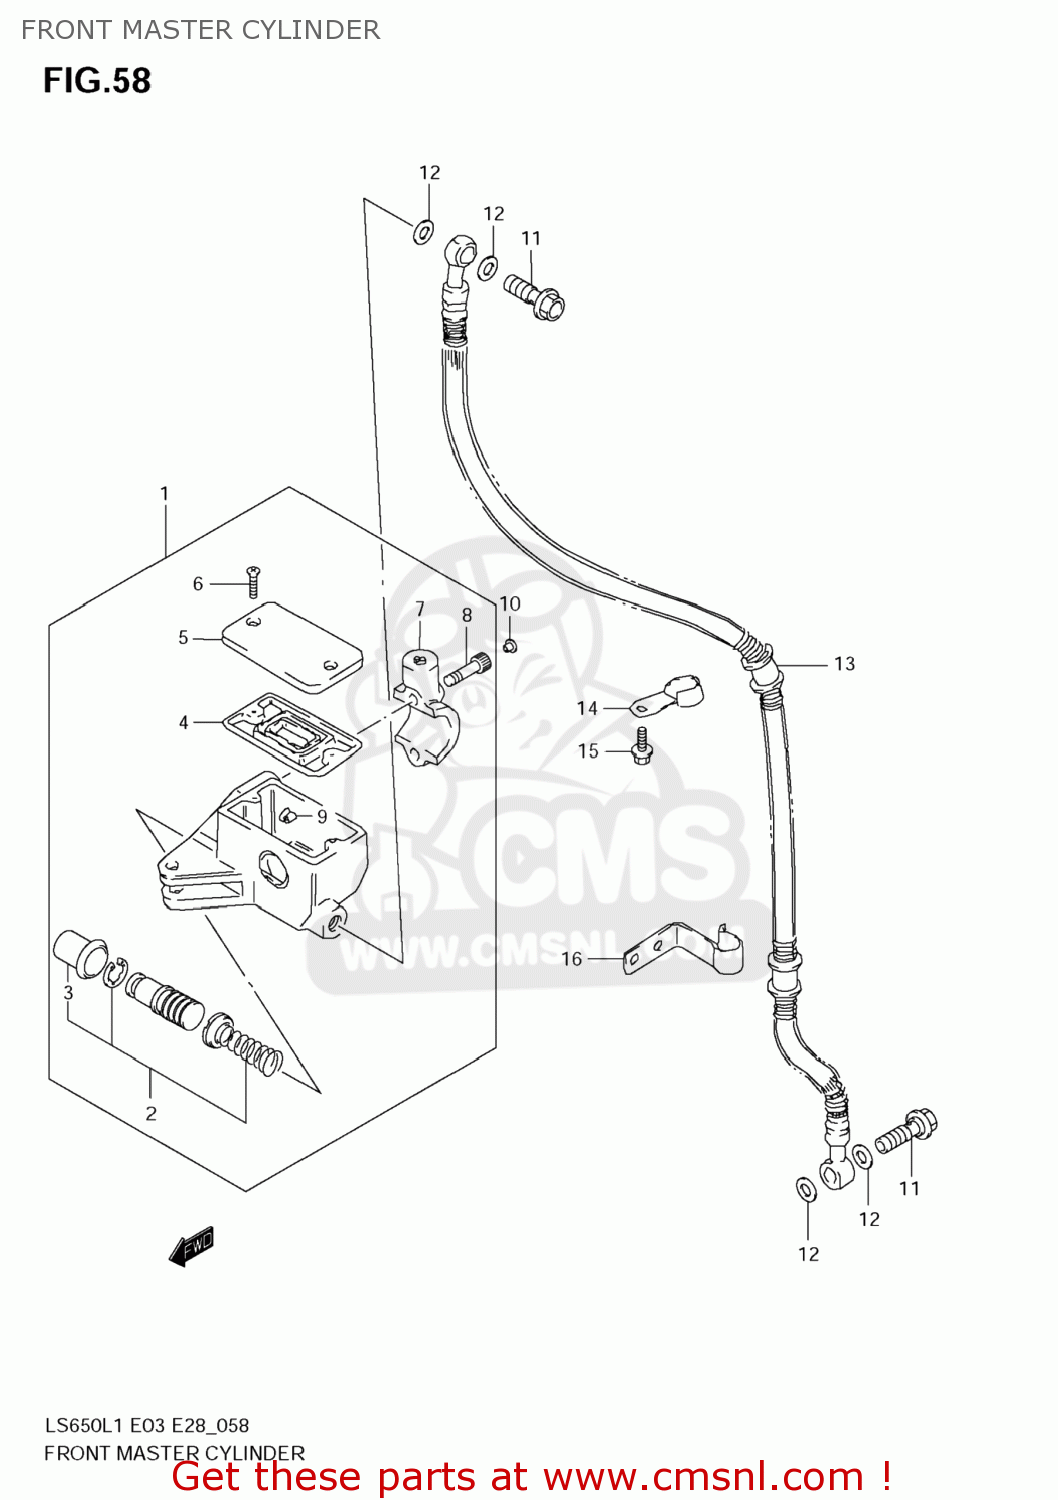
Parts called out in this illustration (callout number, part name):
1	CYLINDER ASSY,FR MASTER
2	PISTON/CUP SET
3	BOOT
4	5
5	CAP
6	SCREW
7	HOLDER
8	BOLT
9	PROTECTOR
10	CAP(OD:10)
11	BOLT UNION
12	WASHER(10X15X1.5)
13	HOSE,FR BRAKE
14	GUIDE,BRAKE HOSE NO.1
15	BOLT
16	GUIDE,BRAKE HOSE NO.2
